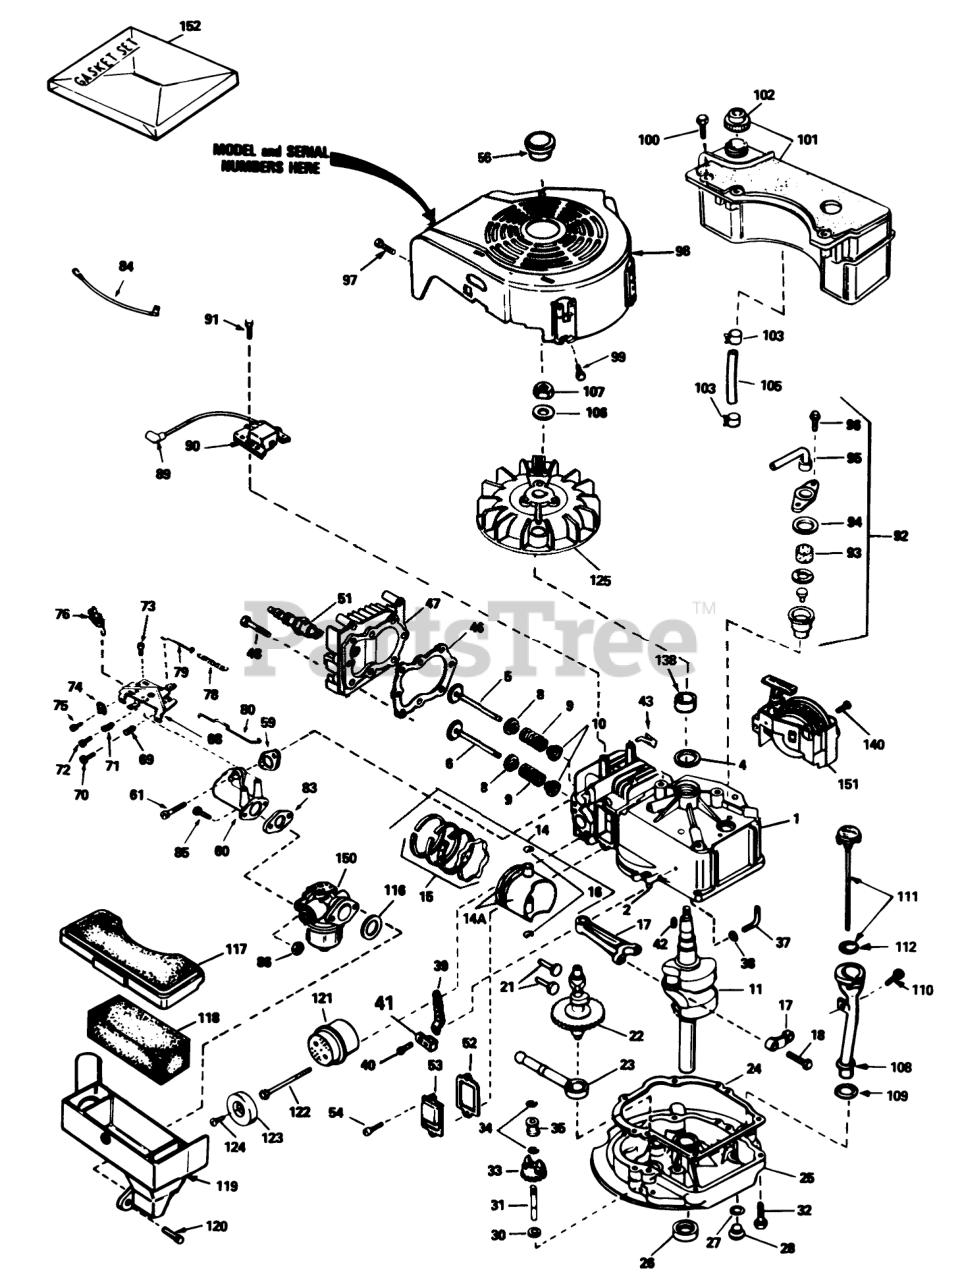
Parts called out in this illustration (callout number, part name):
1	Cylinder Assy. (Incl. #2, 4, 94 & 96)
2	Pin-Dowel
4	Seal-Oil
5	Valve-Intake (Std.)(Incl. #10)
5	Valve-Intake (1/32" oversize)(Incl. #10)
6	Valve-Exhaust (Std.)(Incl. #10)
6	Valve-Intake (1/32" oversize)
8	Cap-Upper Valve Spring
9	Spring-Valve
10	Cap-Valve, Spring
11	Crankshaft
14	Piston-Pin & Ring Assy. (Std.)(Incl. #14A, 15 & 16)
14	Piston-Pin & Ring Assy. (.010 oversize)(Incl. #14A, 15 & 16)
14	Piston-Pin & Ring Assy. (.020 oversize)(Incl. #14A, 15 & 16)
14A	Piston & Pin Assy. (Std.)(Incl. #16)
14A	Piston & Pin Assy. (.010 oversize)(Incl. #16)
14A	Piston & Pin .020 O.S. (Incl. Ref. #25)
15	Piston Ring Set Std.
15	Piston Ring Set .010 O.S.
15	Piston Ring Set .020 O.S.
16	Ring-Retaining, Piston Pin
17	Rod Assy.-Connecting (Incl. #18)
18	Bolt-Rod, Connecting
21	Lifter-Valve
22	Camshaft(Mech.Comp. Release)
23	Oil Pump ASM
24	Gasket
25	Flange Assy.-Mounting (Incl. #26, 27, 28 & 31)
26	Seal Oil
27	Gasket-Oil Drain
28	Plug Oil Drain
30	Washer-Flat
31	Shaft-Governor
32	Screw (1/4-20 x 1-1/4)
33	Gear Assy.-Governor (Incl. #30)
34	Ring-Retaining
35	Spool-Governor
37	Rod-Governor (Incl. #38)
38	Washer-Flat
39	Governor Lever
40	Screw
41	Clamp-Lever, Governor
42	Key-Flywheel
46	Gasket-Cylinder Head
47	2025A67 ADD.ASSEMBL
48	Screw (5/16-18x1-1/2)
51	Plug, Spark (J17LM or equiv.)
51	Plug, Spark (Champion RCJ-8)
52	Gasket-Breather
53	Cover-Valve
56	Plug, Screen
59	Gasket-Intake
60	Pipe-Intake (Incl. #59)
61	Screw (1/4-20 x 1)
68	Control Assy.-Remote Speed (Incl. #69-72 & 76)
69	61709/GIL1515A/95-5
70	Screw
71	Spring-Compression
72	Screw
73	Screw (10-24 x 9/16)
74	Conduit
75	Screw (10-32 x 3/8)
76	Terminal
78	Spring Governor
79	2035A67 ADD.ASSEMBL
80	Link-Throttle
83	Gasket
84	Wire-Ground
85	Screw (1/4-28 x 7/8)
86	Nut and Lock Washer (1/4-28)
89	Cover-Spark Plug
90	Solid State
91	Screw
92	Breather Assy. (Incl. #93-96)
93	Element-Breather
94	Gasket-Breather
95	Tube, Breaker
96	Screw (10-24 x 9/16)
97	Screw (10-24 x 9/16)
98	Housing-Blower
99	Screw (1/4-20 x 1/2)
100	Screw (10-32 x 35/64)
101	Tank Assy.-Fuel (Incl. #102)
102	Cap-Fuel
103	Clamp-Line, Fuel
105	Line-Fuel
106	Washer-Belleville
107	Nut-Flywheel
108	Tube-Oil Fill
110	Screw (10-32 x 1/2)
111	Dipstick-Oil (Incl. #112)
116	Gasket-Cleaner, Air
117	Cover Air Cleaner
118	Filter-Air Cleaner
119	Body Air cleaner
121	Muffler (Incl. #122)
123	Cover-Muffler
124	Screw
125	Flywheel
140	Screw (1/2-20x5/8)
150	Carburetor (Incl. #83)
151	Starter-Sidemount
152	Gasket Set
